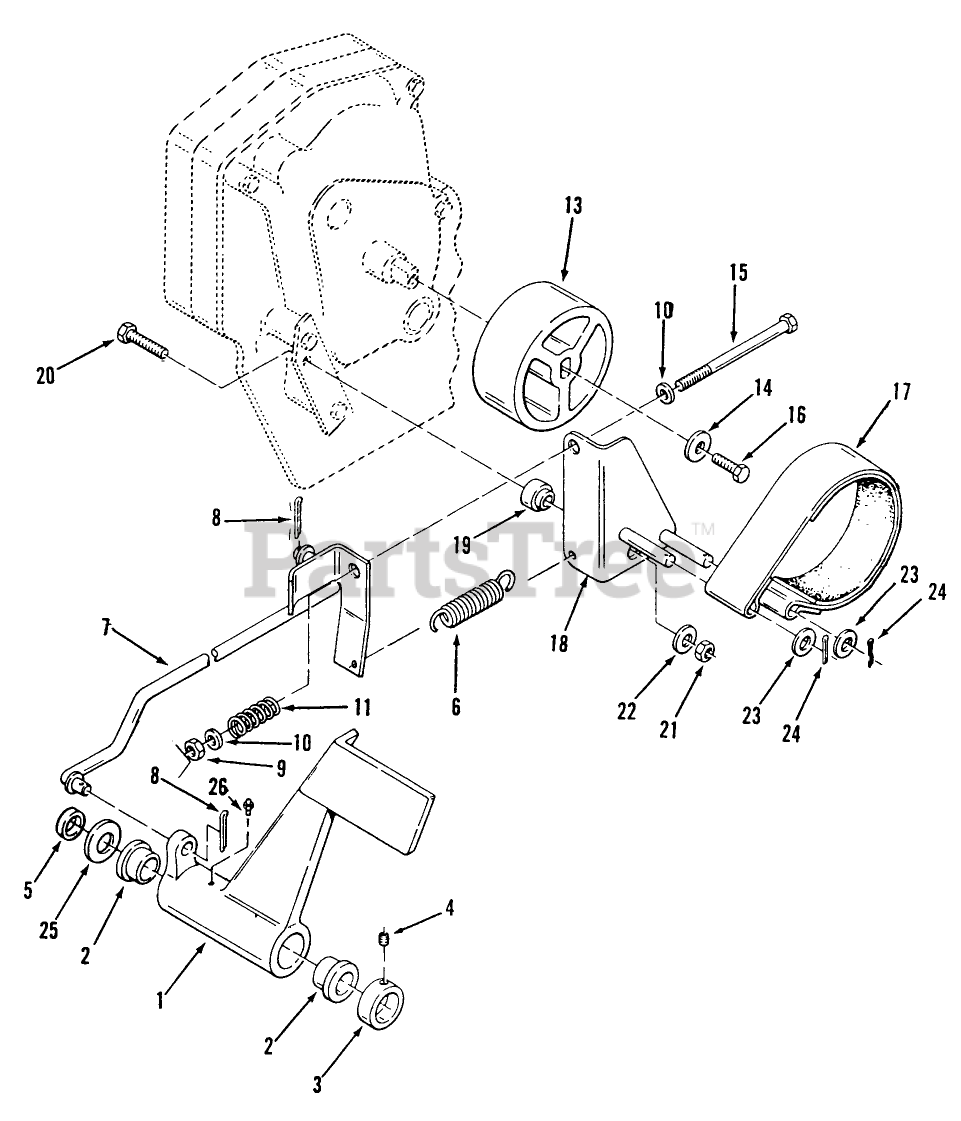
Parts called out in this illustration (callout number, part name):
1	Brake/Return To Neutral Pedal
2	BUSHING
3	COLLAR *R
5	SPACER-OUTER
6	SPRING
11	SPRING-COMPRESSION
13	DRUM-BRAKE
14	WASHER
17	ASSY-BRAKE BAND
25	WASHER
